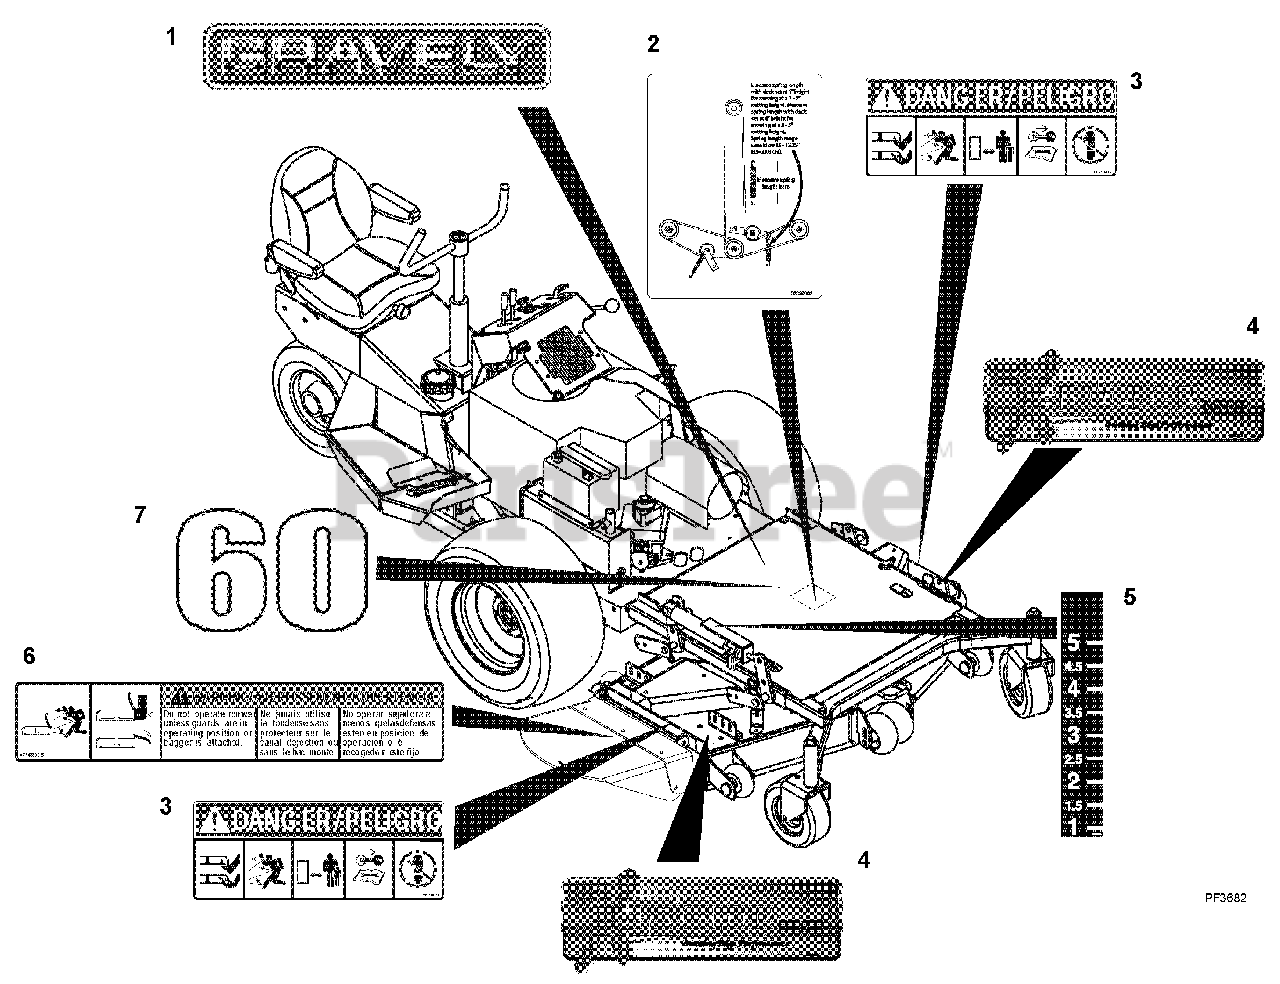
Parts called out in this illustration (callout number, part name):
1	Decal-15" Gravely Logo
2	Decal, Belt Diagram
3	Decal, Mower Pan Head Danger
4	Decal, X-Factor Deck
5	Height of Cut
6	Decal, Warning
7	Decal, 60
